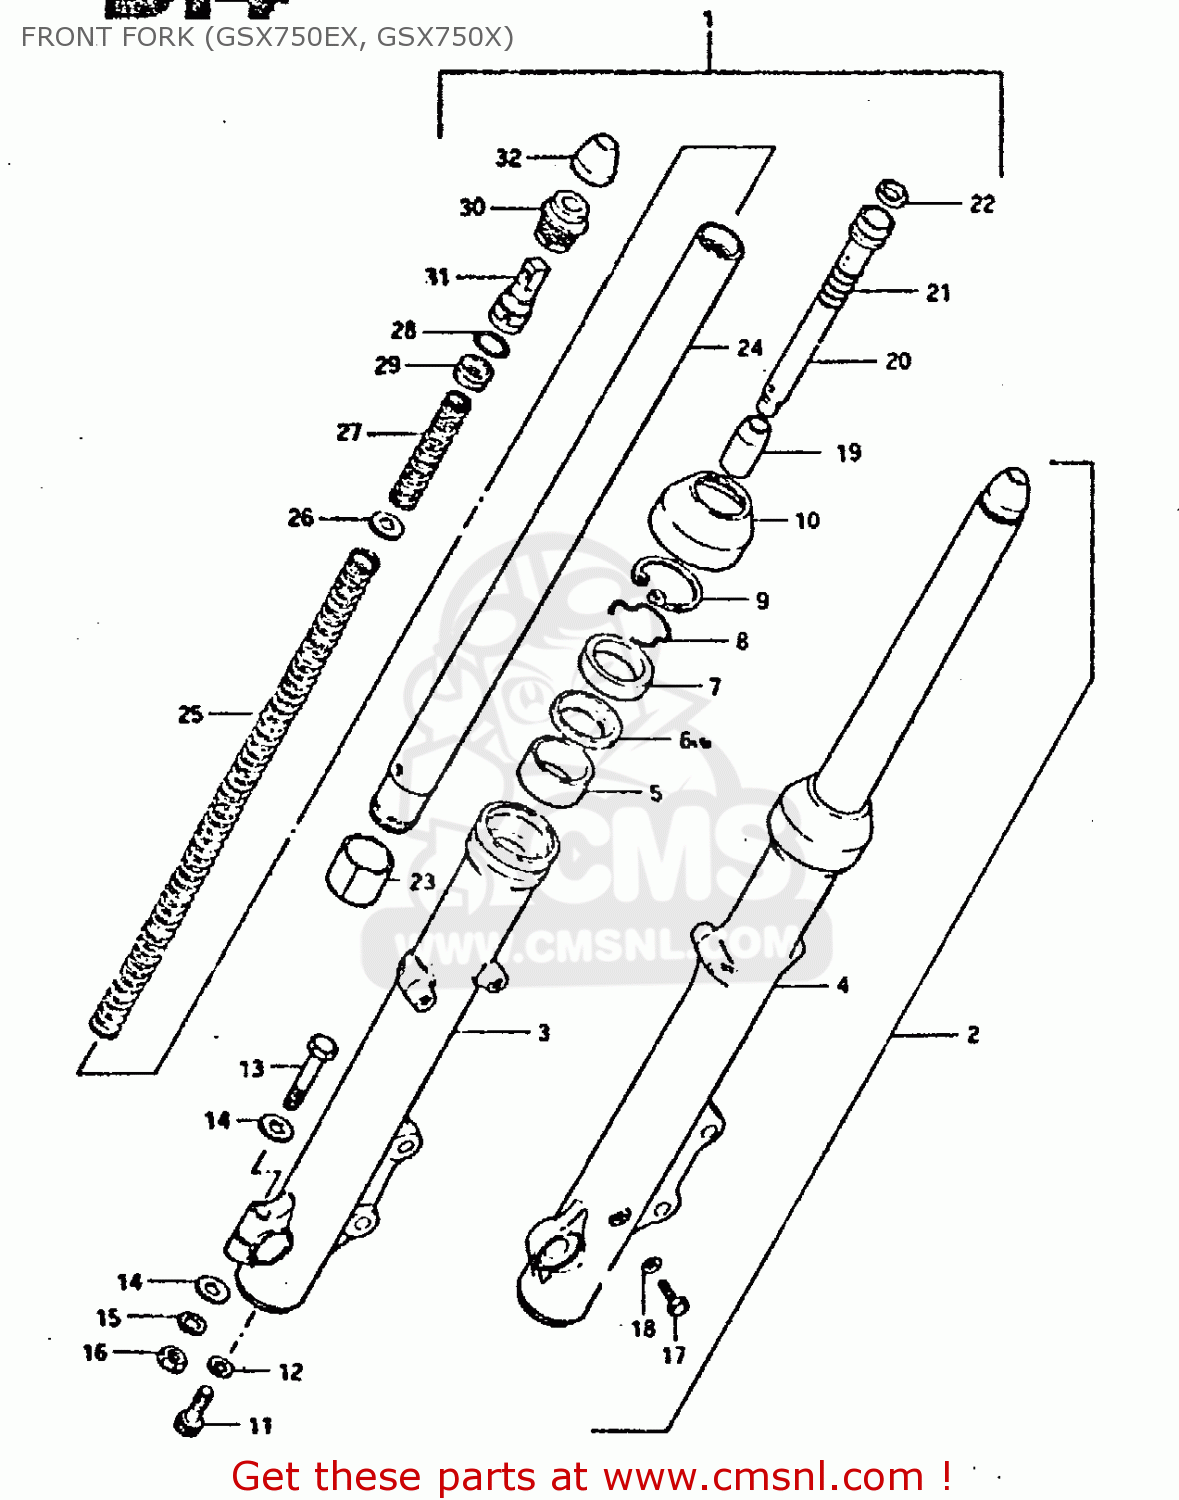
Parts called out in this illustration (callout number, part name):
1	DAMPER ASSY, RH
2	DAMPER ASSY, LH
3	TUBE,FORK,OUTER,RIGHT
4	TUBE,FORK,LEFT,OUTER
5	BUSH,GUIDE
6	SPACER,SEAL
7	OIL SEAL,FRONT FORK
8	RING,FR FORK
9	CIRCLIP,FORK OIL SEAL
10	BOOT
11	BOLT(8X27)
12	GASKET (NAS)
13	BOLT 8X50
14	WASHER
15	LOCK WASHER
16	NUT
17	BOLT(6X8)
18	GASKET,DRAIN,PLUG (NAS)
19	PIECE,OIL LOCK
20	CYLINDER
21	SPRING,FORK REBOUND
22	RING
23	PISTON
24	INNER, TUBE
25	SPRING B
26	WASHER,SPRING
27	SPRING A
28	O-RING
29	SEAT, SPRING
30	BOLT
31	ADJUSTER, SPRING
32	CAP
